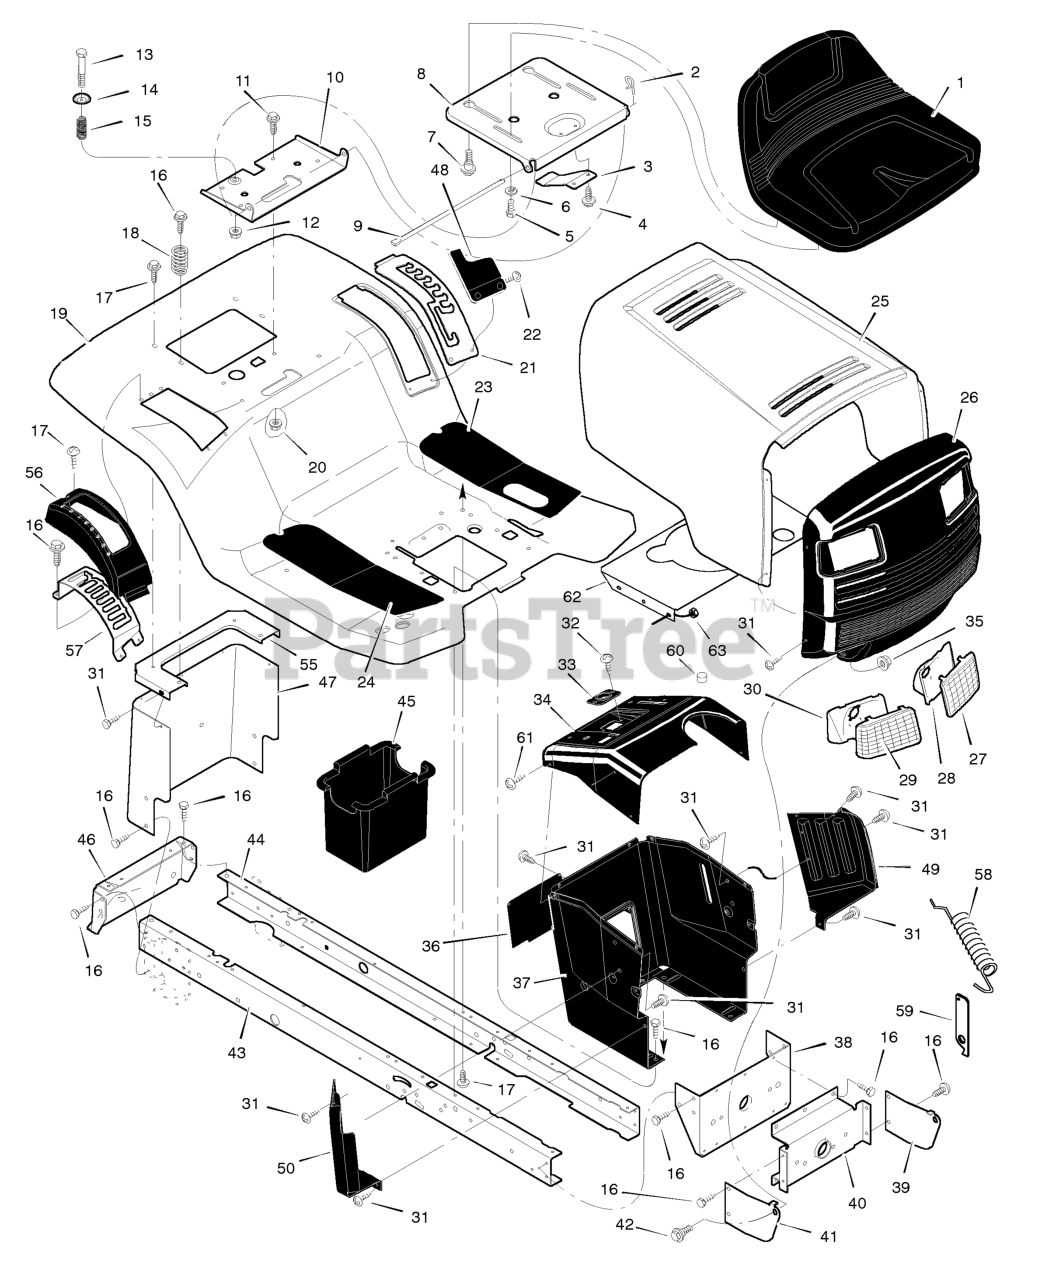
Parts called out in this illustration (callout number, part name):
2	Cap, Push On
5	Bolt, Wing
6	Washer
7	Bolt, Shoulder
8	Support, Seat
9	Rod, Pivot
10	Bracket, Pivot
11	Bolt
13	Bolt, Shoulder
15	Spring
19	Deck, Seat
20	Nut
21	Plate, Index
23	Mat, Left
24	Mat, Right
27	Lens, Left
28	Bezel, Left
29	Lens, Right
30	Bezel, Right
31	Screw
33	Bearing, Steering
35	Nut
36	Panel, Access
37	Support, Dash
38	Bracket, Rear Hanger
39	Support, Left Grille
40	Axle, Hanger
41	Support, Right Grille
42	Bolt, Shoulder
43	Frame, Right
44	Frame, Left
45	Container, Battery
46	Plate, Hitch
47	Panel, Rear
48	Cover, Level Adjustment
49	Panel, Left Side
50	Panel, Right Side
55	Plate, Rear
56	Cover, Shift Gate
57	Shift Gate
58	Extension, Spring
59	Bracket
60	Bumper
62	Deflector, Heat
63	Nut, Heat Deflector
